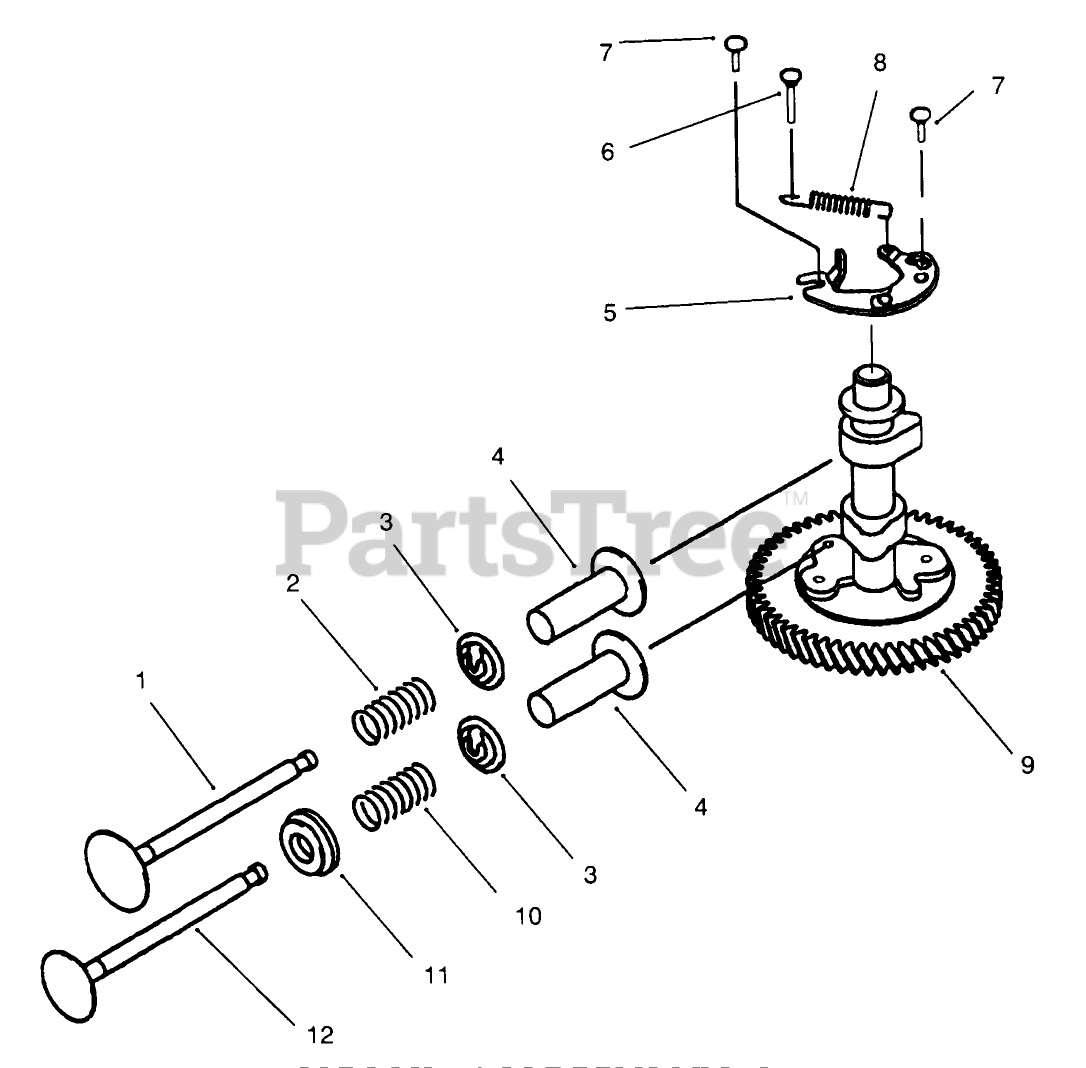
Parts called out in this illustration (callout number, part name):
1	Intake Valve
2	Spring-Valve
3	Retainer-Spring
4	Tappet
5	Decompressor
6	Pin
7	Pin
8	Spring
9	Camshaft-Complete (Incl. Ref. #5-8)
10	Spring-Valve
11	Rotator
12	Exhaust Valve
